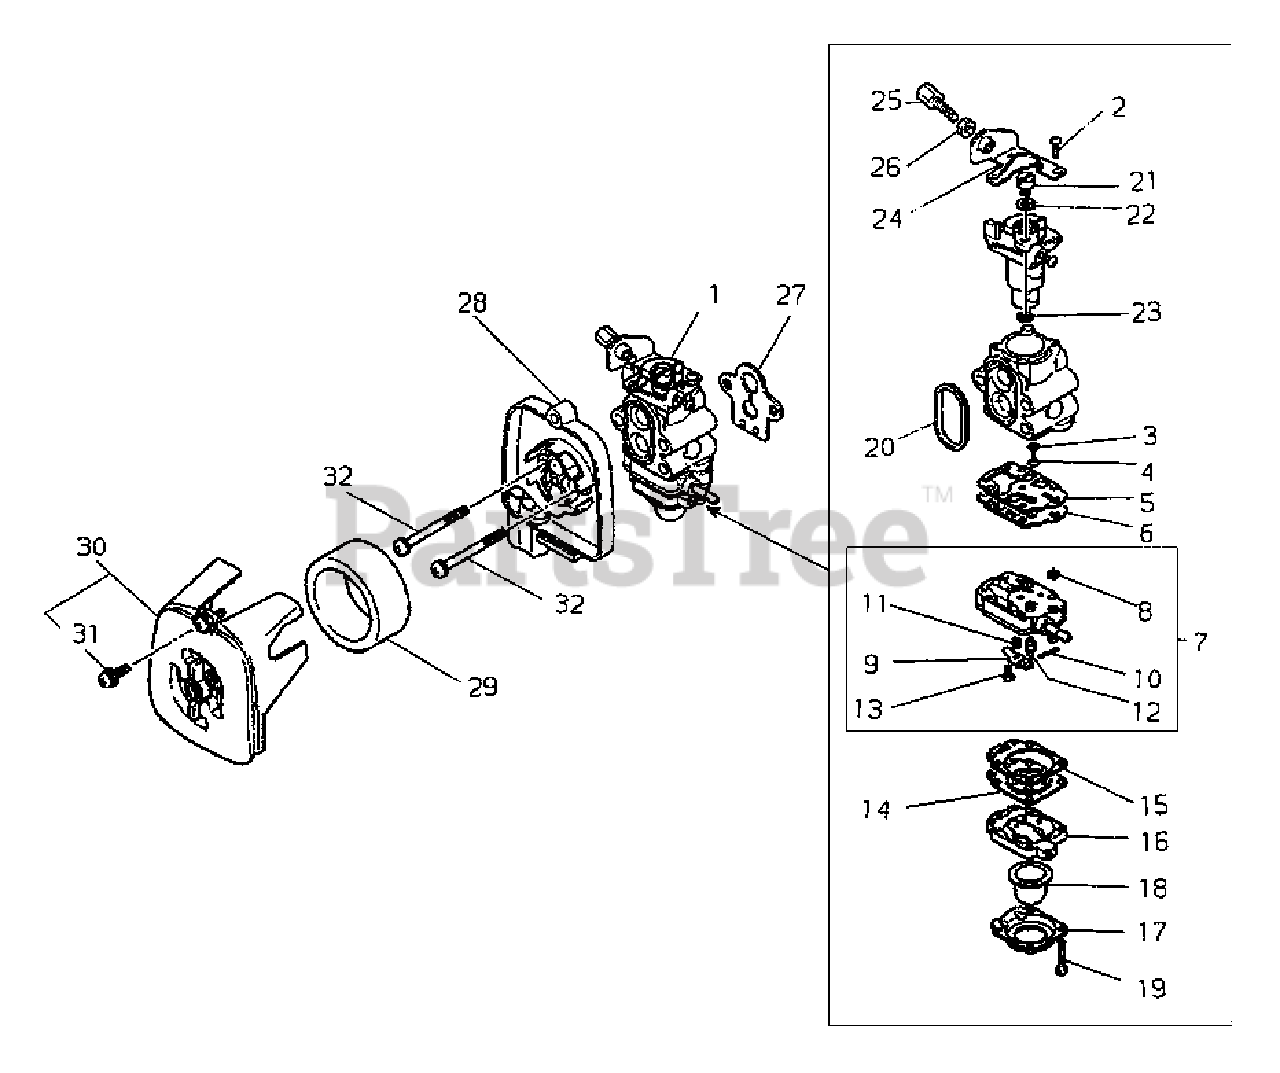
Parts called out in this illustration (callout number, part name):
1	CARBURETOR
4	JET, MAIN
5	PUMP GASKET
6	DIAPHRAGM
7	BODY PUMP COMP.
8	SCREEN
9	LEVER
10	PIN
11	SPRING
12	VALVE, NEEDLE
13	SCREW
14	DIAPHRAGM
16	BASE, PURGE
17	COVER, PUMP
18	BULB, PURGE
20	RING GASKET
24	BRACKET, CABLE
25	ADJUSTER, CABLE
27	GASKET
28	CASE, AIR FILTER
29	FILTER
30	AIR FILTER COVER ASSY
31	SCREW
